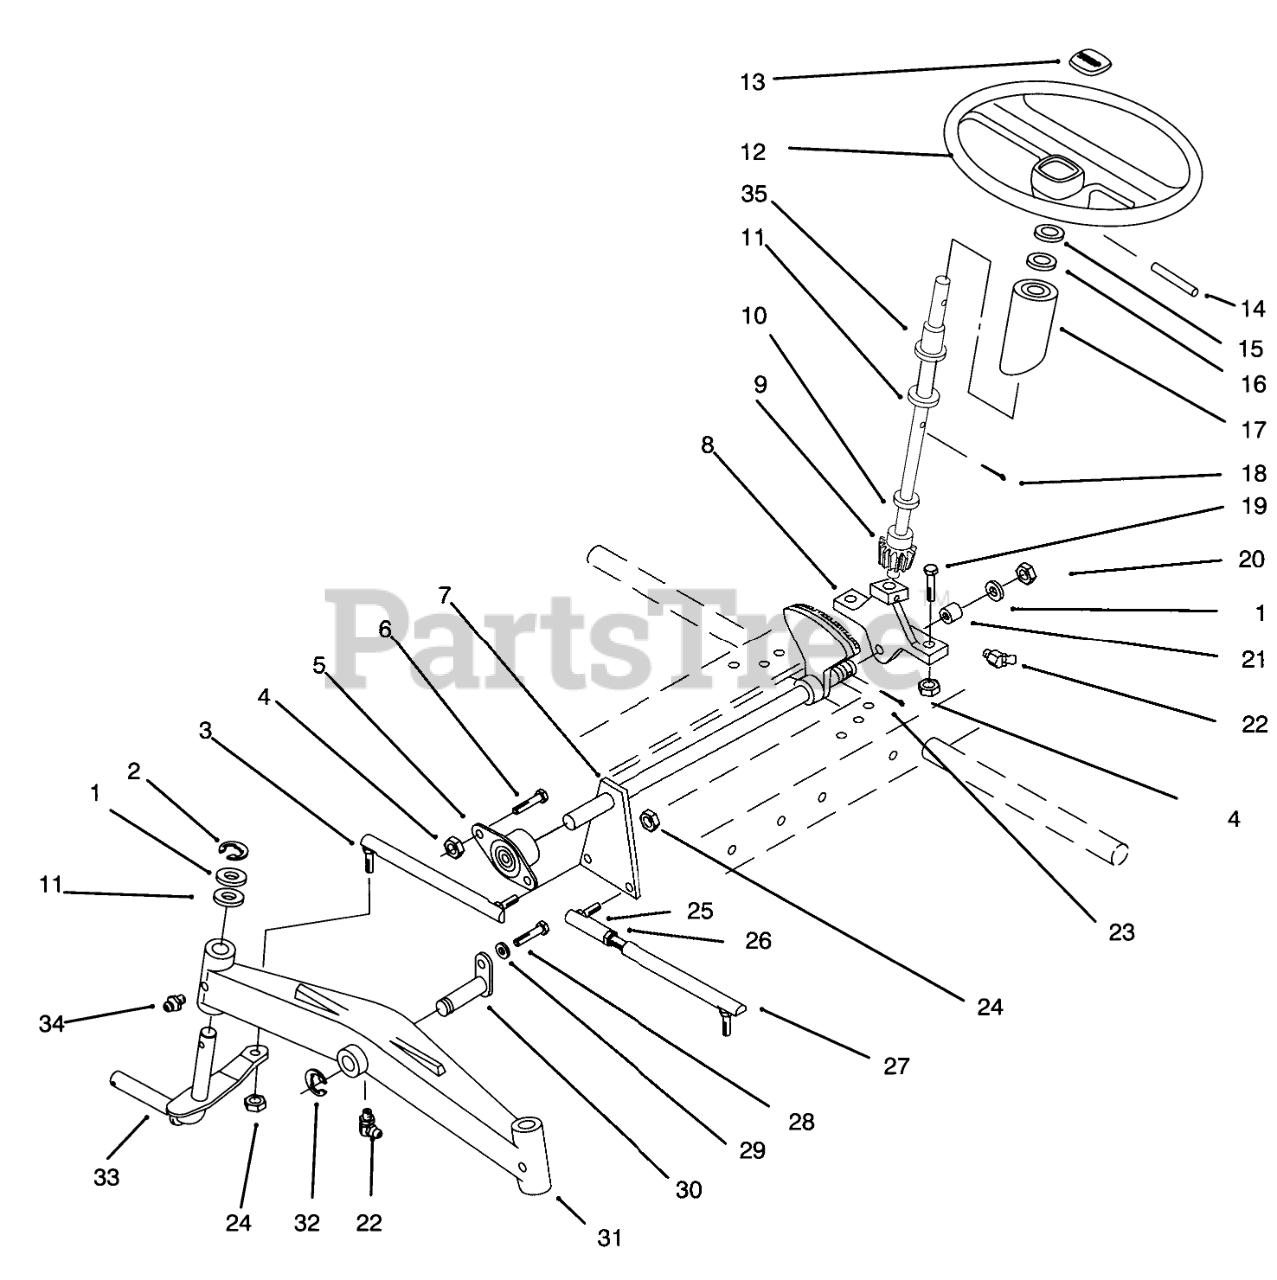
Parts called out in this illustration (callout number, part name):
1	WASHER
2	RING-RETAINING
3	Tie Rod RH
4	NUT-LOCK, NI
5	BEARING-FLANGED
6	SCREW-HH
7	Shaft
8	Support-Steering
9	STEERING SHAFT ASM
10	O-RING
11	WASHER-SHIM
12	Steering Wheel (Incl. Ref. #13)
13	STRG-WHL INSERT TORO
14	PIN-ROLL
15	WASHER-BOWED
16	WASHER-FLAT
17	TUBE-STEERING
18	PIN-COTTER
19	SCREW-HH
20	NUT-HEX, SLOTTED
21	BEARING-BRONZE
22	FITTING-GREASE
23	PIN-COTTER
24	NUT-LOCK
25	BALL-JOINT
26	NUT-HEX
27	Tie Rod Assembly, LH (Incl. Ref. #25 & 26)
28	SCREW-HH
29	WASHER-LOCK
30	PIN AND PLATE ASM
31	AXLE-FRONT
32	E-RING
33	LH SPINDLE ASM
34	FITTING-GREASE
35	BEARING-FLANGED
